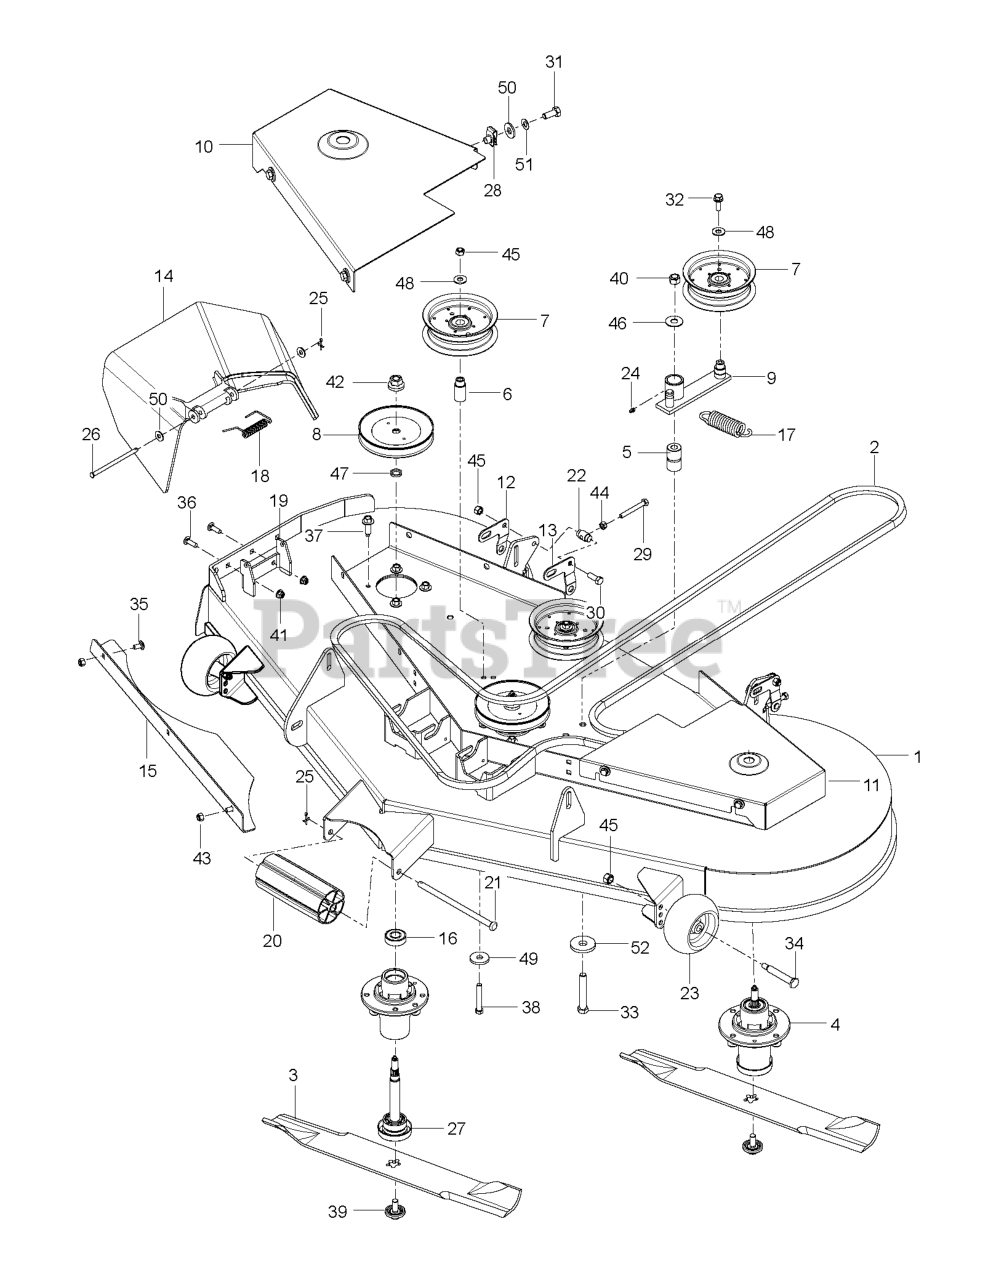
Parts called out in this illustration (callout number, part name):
1	DECK SVC MZT 61 W/DECALS ORG
2	BELT, DECK
3	BLADE, 21"
4	MANDREL.DECK.ASSEMBLY
5	PIVOT BUSHING
6	IDLER BUSHING
7	PULLEY.IDLER.DECK
10	BELT SHIELD, RH ORANGE
11	BELT.SHIELD.LH.ORANGE
12	BRACKET.RT.PNT.MS431
13	BRACKET.LH.PNT.MS431
14	DISCHARGE CHUTE 61"
15	CONFINEMENT PLATE 61
16	BEARING
16	BEARING, BALL
17	SPRING EXTENSION DECK BELT BLA
18	SPRING - TORSION
19	BRACKET MZ CHUTE ORANGE MS-668
19	BRACKET MZ CHUTE
20	NOSE ROLLER 48"
21	ROD.ROLLER.NOSE.NARROW.48"
22	TRUNION, PITCH
23	WHEEL GAGE DONUT
24	ZERK
25	RP_COTTER PIN 1/8 X 3/4
26	COTTER PIN
26	PIN-CLEVIS 5/16 DIA X 5.19 ZD
27	SHAFT ASM MANDREL
28	U-CLIP 5/16-18 NUT RETAINER
29	HCS 5/16-18 X 2 1/2 TPBLT
30	HCS 3/8-16X1.GRD.5.ZD
31	HCS 5/16C X 3/4
32	4CS 3/8C X 1 SERRATED HEAD
33	HCS 1/2-13 X 3-1/4 GD 5 ZD
34	BOLT, SHOULDER
34	SHOULDER BOLT 1/2X2-5/8 ZD SPE
35	CARRIAGE BOLT 5/16C X 5/8"
36	RHSSNB 5/16C X 1.0
37	BOLT.HEX.WASHR.HED.313-18X1.19
37	WASHER HEAD SCREW
38	WASHER HEAD SCREW
38	BOLT.HEX.FIN.3/8-16 X 3.GR5
39	BOLT.WASHER.ASM.7/16-2
40	NUT 1/2-13 HEX NYLOC ZD
41	5/16-18 NYLOC FLANGE NUT
42	NUT.FLANGE.LOCK.TOP
43	NUT 5/16 NYLOC
44	NUT 5/16C HEX
45	NUT 3/8-16 NYLOC
46	WASHER 1/2 FLAT
47	WASHER.SPACER.MANDREL
48	RP WASHER 3/8 FLAT
49	SPINDLE WASHER
50	WASHER.5/16.FLAT.STE.STD.
51	WASH 5/16 DISC SPRING ZD
52	WASHER, SUPPORT
